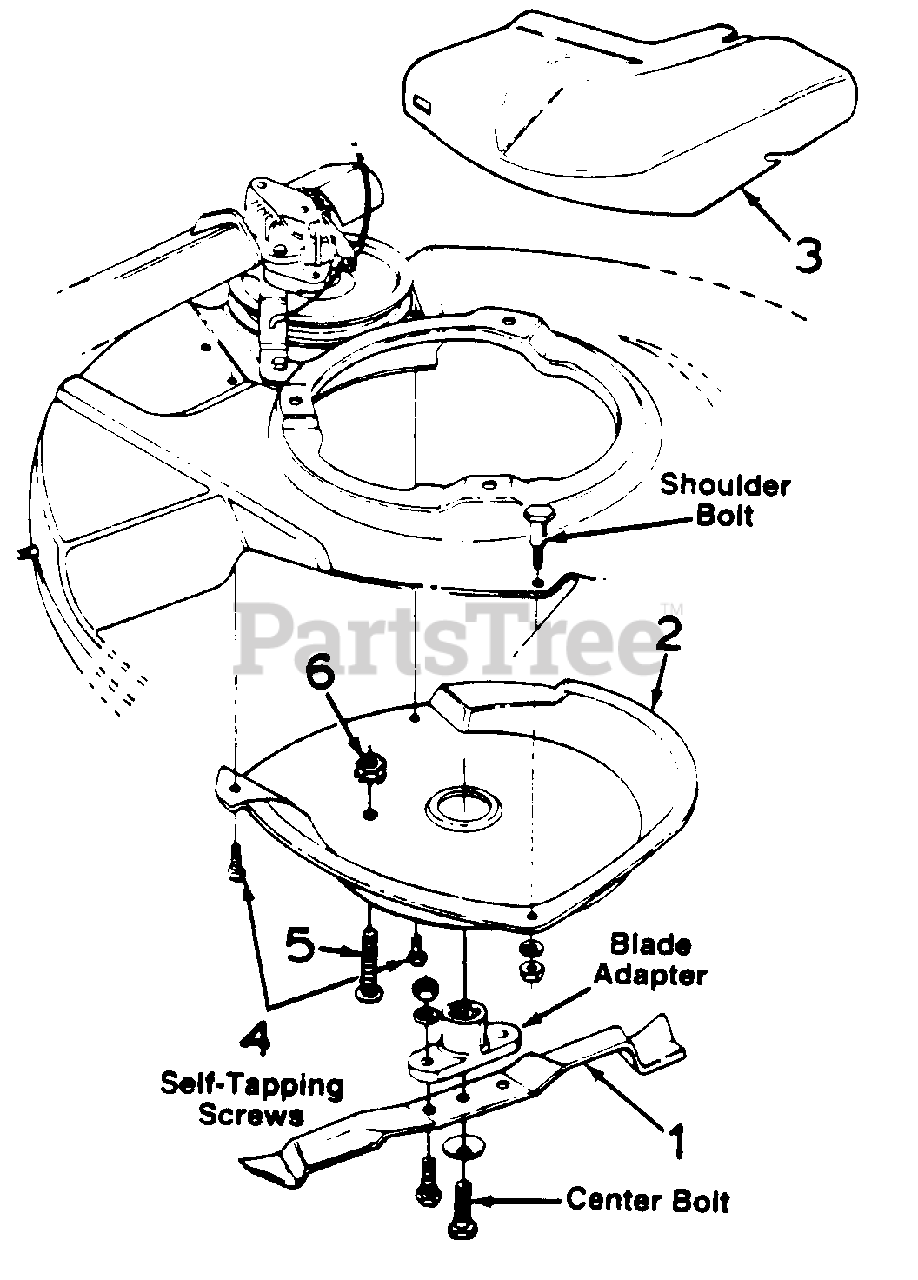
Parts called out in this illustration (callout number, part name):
1	Mulching Blade
4	Self-Tapping Screw
5	Phillips Scr. 1/4-20 x 1.5" Lg.
6	Hex Sems Nut 1/4-20 Thd.
